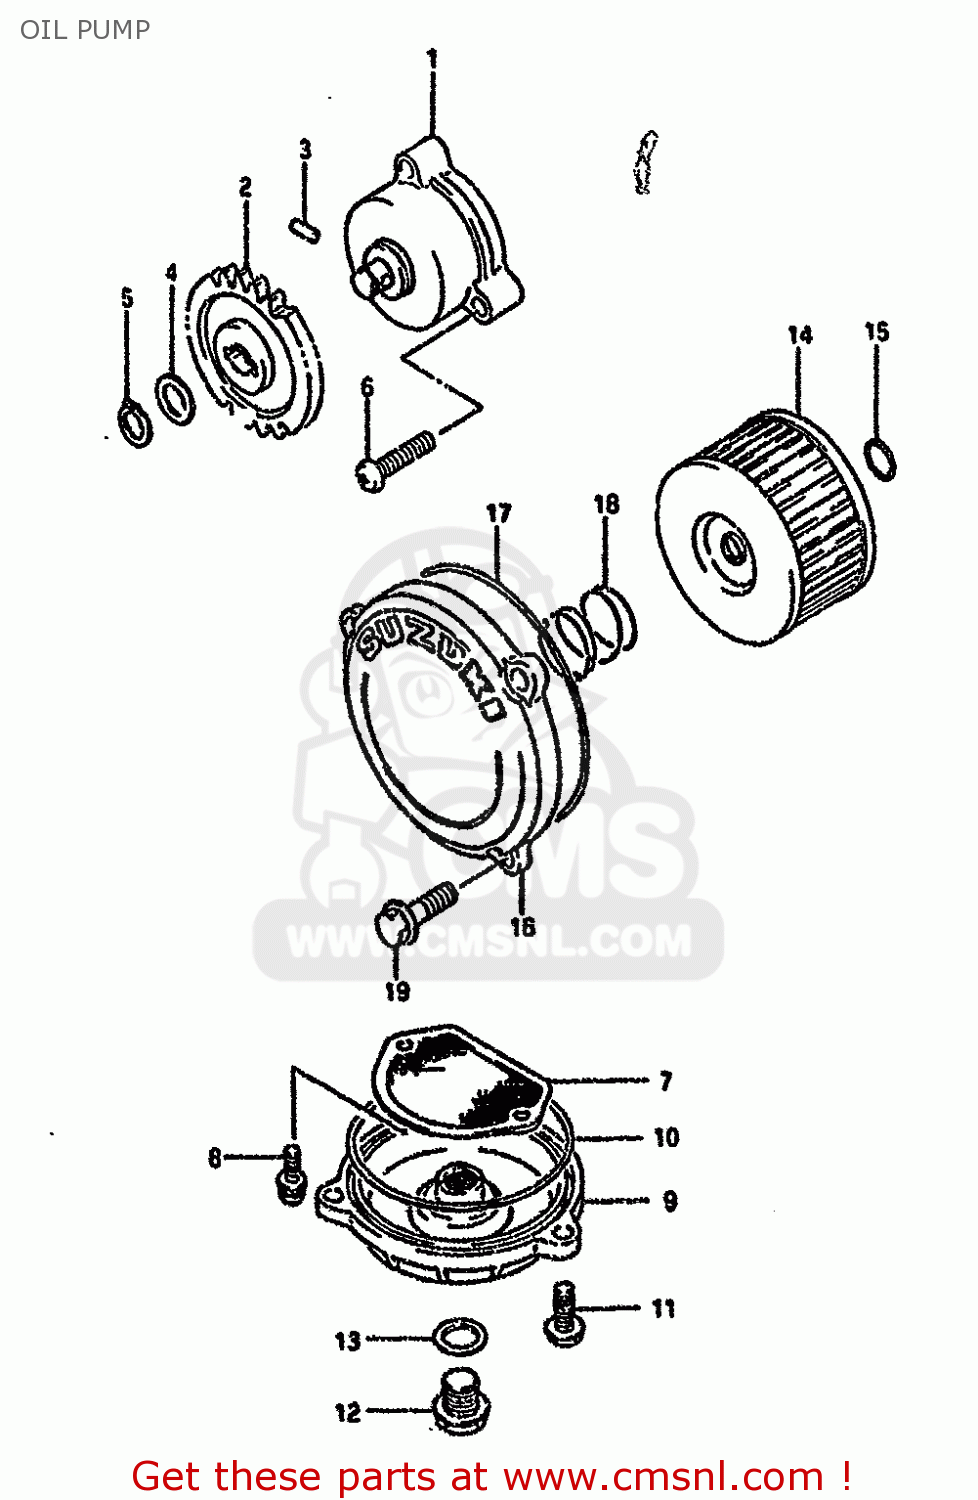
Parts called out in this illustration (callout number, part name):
1	PUMP ASSY,ENGINE OIL
2	GEAR,OIL PUMP DRIVEN
3	PIN(4X15.8)
4	SHIM
5	CIRCLIP,10MM
6	SCREW
7	STRAINER,ENGINE OIL
8	SCREW
9	CAP,OIL STRAINER
10	O RING(D:2.4,ID:85)
11	BOLT
12	PLUG
13	GASKET(14X19.2X2) (NAS)
14	FILTER,ENGINE OIL
15	O RING(D:2.4,ID:15.8)
16	CAP,OIL FILTER
17	O RING(D:2.4,ID:73)
18	SPRING
19	BOLT
